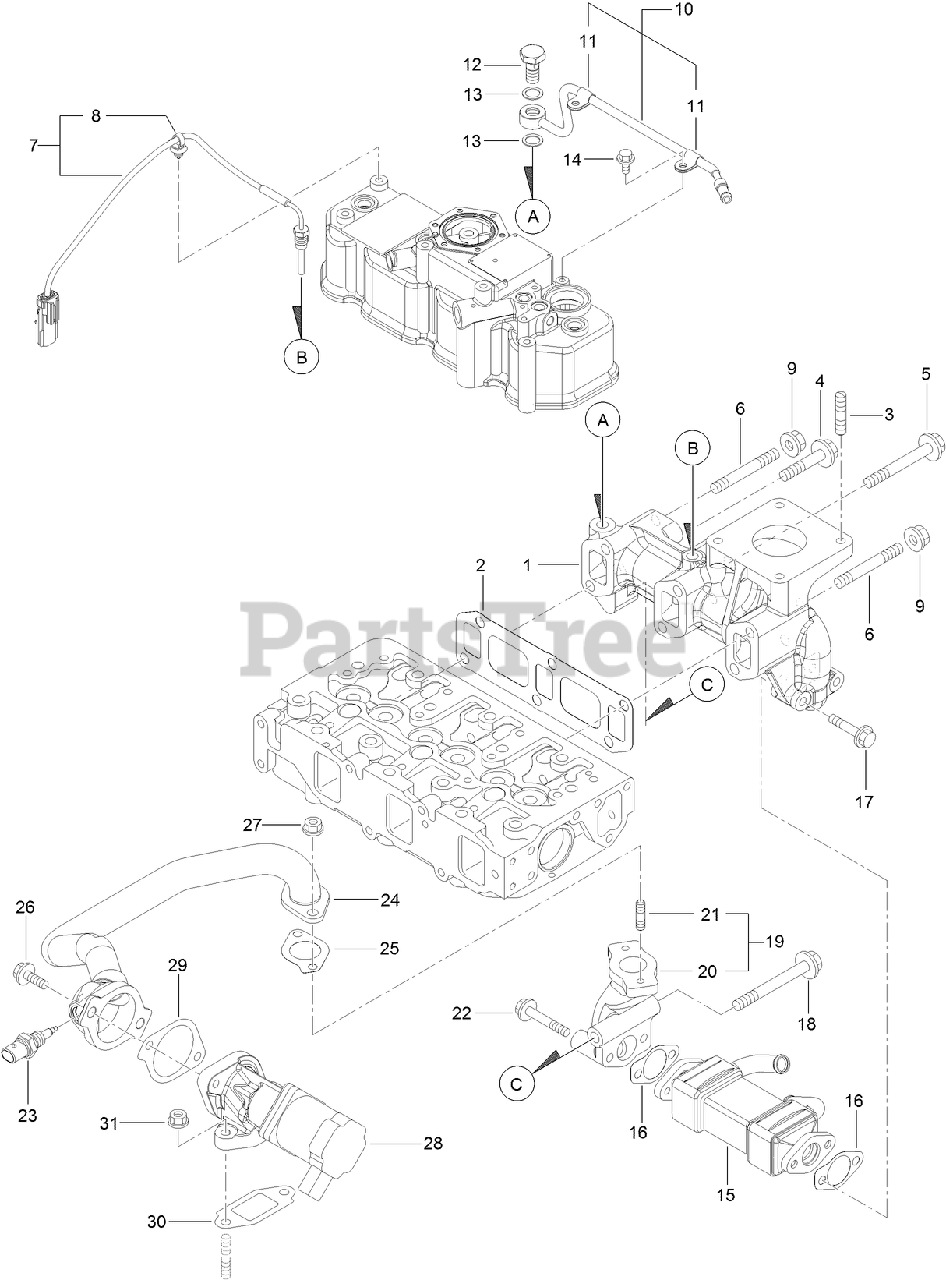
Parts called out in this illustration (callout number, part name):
1	MANIFOLD-EXHAUST
2	GASKET-MANIFOLD, EXHAUST
5	BOLT-M10
7	SENSOR-TEMP, EXHAUST
8	BAND-CLIP
10	EXHAUST PIPE ASM
12	BOLT-JOINT, PIPE
13	GASKET
15	COOLER-E G R
16	GASKET-COOLER, E G R
18	BOLT-FLANGE
19	E G R PIPE ASM
20	PIPE-OUT, E G R
23	SENSOR-GAS TEMP, E G R
24	E G R PIPE ASM
25	GASKET
28	VALVE-E G R
29	GASKET-INTAKE VALVE, E G R
30	GASKET-OUT VALVE, E G R
